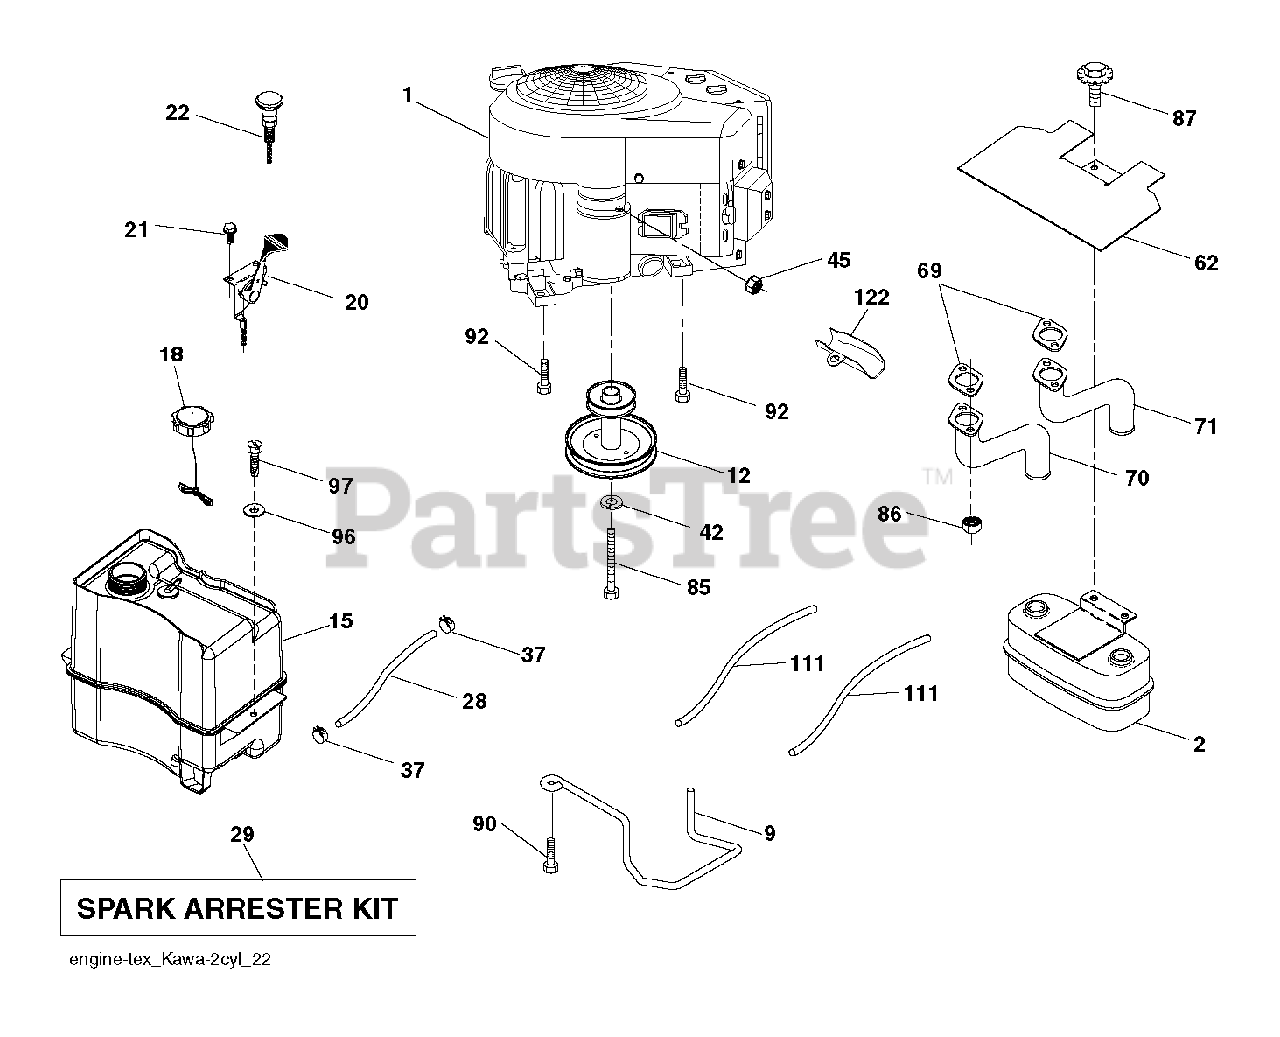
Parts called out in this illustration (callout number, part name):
2	MUFFLER.ASM.TWN.EXTNDED.DFLCTR
9	KEEPER.BELT.ENGINE.4.2
12	PULLEY ENGINE
15	TANK.ASM.FRT.2.5 GAL.W/CAP.EPA
18	CAP.2.25'.VENTED.TETHER .EPA
20	CONTROL.THROTTLE.COBRA.BLACK
21	SCREW.#10 X 0.750.BOS
22	CONTROL, CHOKE
28	REPL BY 532 00 85-43
29	KIT.SPARK ARRESTOR 794945 B&S
37	HOSE CLAMP
42	LOCKWASHER
45	NUT
62	SHIELD.HEAT.MUFFLER
69	GASKET.EXHAUST.KOHLER
70	TUBE.EXHAUST.RH.FR961/FR730
71	TUBE.EXHAUST.LH.FR961/FR730
85	BOLT HEX 7/16-20X4-1/4"
86	BLADE ADAPTER
87	Bolt, 5/16-18 X 1-3/4
90	SCREW 3/8-16X1
92	SCREW 3/8-16X1
97	SCREW HEXWSHR 1/4-20X3/4
111	RP PURGE LINE
122	EXTENSION DRAIN OIL
